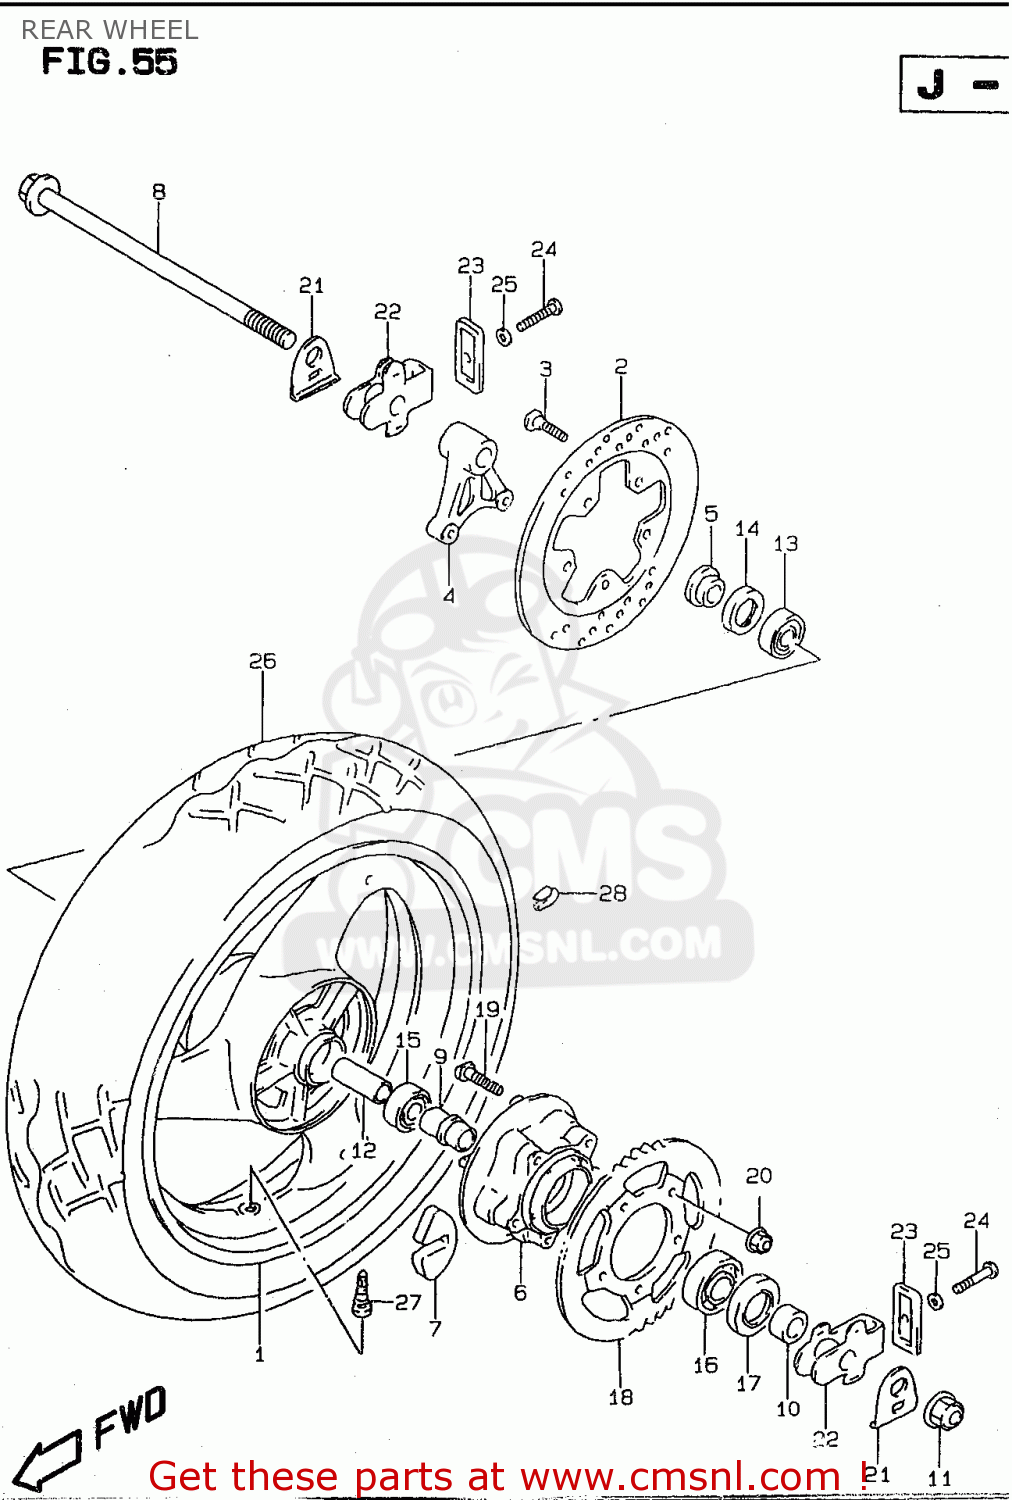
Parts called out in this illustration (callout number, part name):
1	WHEEL,RR(MT4.50X17)
2	DISC,RR BRAKE
3	BOLT 8X33
4	BRACKET,RR CALIPER
5	SPACER,RR AXLE,R
6	DRUM,RR SPROCKET
7	ABSORBER,RR HUB SHOCK
8	AXLE,RR
9	RETAINER,RR HUB BEARING
10	SPACER,RR AXLE,L
11	NUT ,18MM
12	SPACER(20.8X27.2X97)
13	BEARING
14	SEAL,OIL(28X47X7)
15	BEARING(20X47X14)
16	BEARING(25X62X17)
17	SEAL,OIL(35X62X8)
18	SPROCKET,RR(NT:47-530)
19	BOLT(10X47)
20	NUT
21	WASHER,CHAIN ADJUSTER
22	ADJUSTER,CHAIN
23	PLATE,CHAIN ADJUSTER GUIDE
24	BOLT(8X50)
25	WASHER
26	TIRE,REAR 150/70-17 69
27	VALVE ASSEMBLY,WHEEL,TR412
28	BALANCER,WHEEL (10G)
